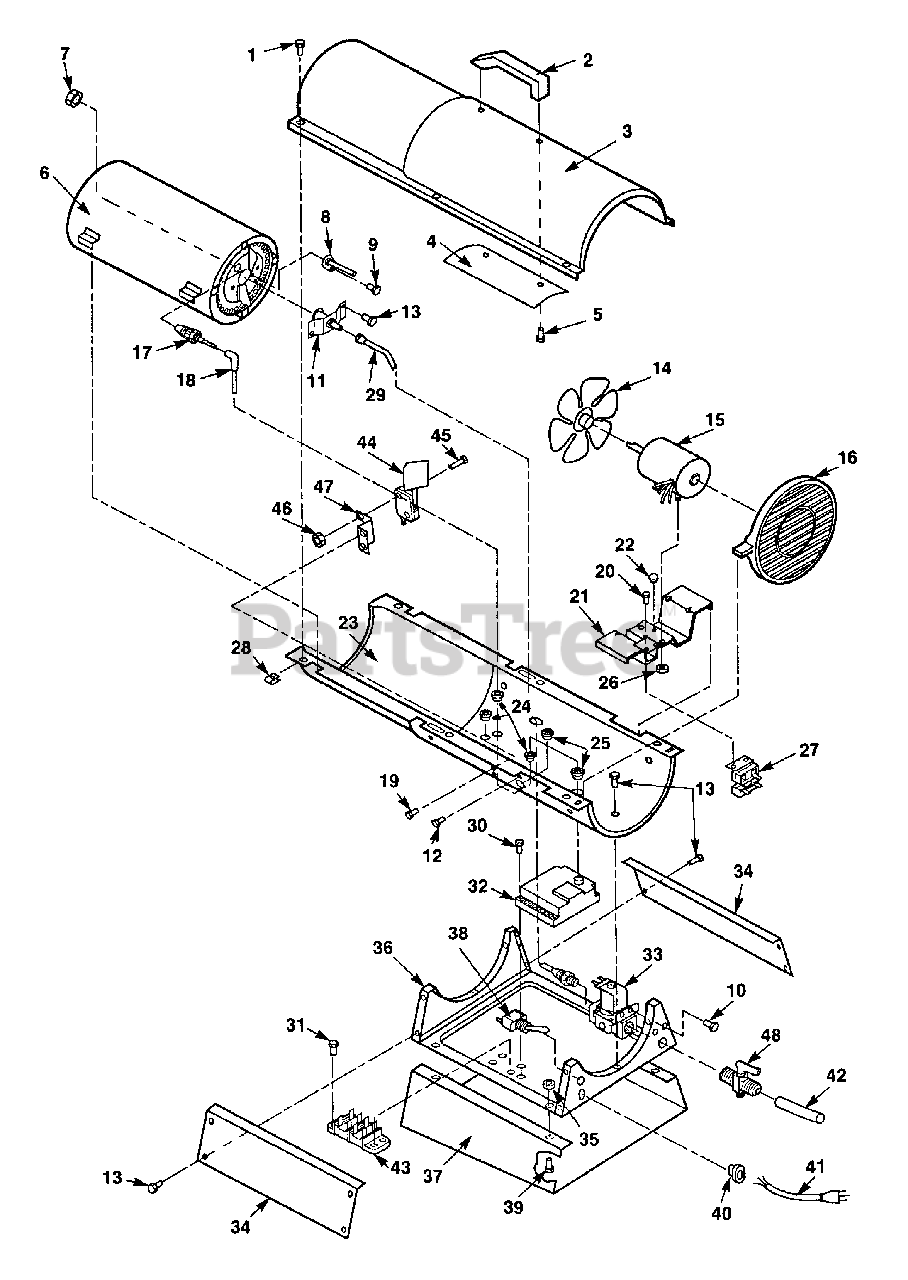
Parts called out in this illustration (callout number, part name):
3	SHELL- Upper
4	SHIELD- Heat
6	COMBUSTION CHAMBER
7	NUT- 14mm
8	SENSOR- Flame
11	ASSY. NOZZLE
12	SCREW- #8-18 x 3/8"
15	MOTOR
16	GUARD- Fan
17	PLUG- Spark
18	CABLE- Ignition
20	SCREW-#8-32 x 1/4"
21	BRACKET- Motor
22	BUMPER- Rubber
23	SHELL- Lower
24	BUSHING- Snap
25	BUSHING- Shorty
26	NUT- Hex Jam
28	NUT- Clip
29	TUBE- Fuel
30	SCREW- #6-20 x 7/8"
31	SCREW- #8-15 x 1/2"
32	CONTROL D.S.I.
33	SOLENOID VALVE
34	COVER- Side
35	NUT- 1/4-20
36	LOWER SHELL CRADLE
38	SWITCH- On/Off
39	BOLT- 1/4-20 x 3/8"
40	BUSHING- Strain Relief
41	CORD- Power
42	CAP- Sleeve
43	BOARD- Terminal
44	AIR SWITCH
45	SCREW- #4-40 x 3/4"
46	NUT- #4-40
47	BRACKET- Air Switch
48	VALVE- Shut-Off LP Gas
